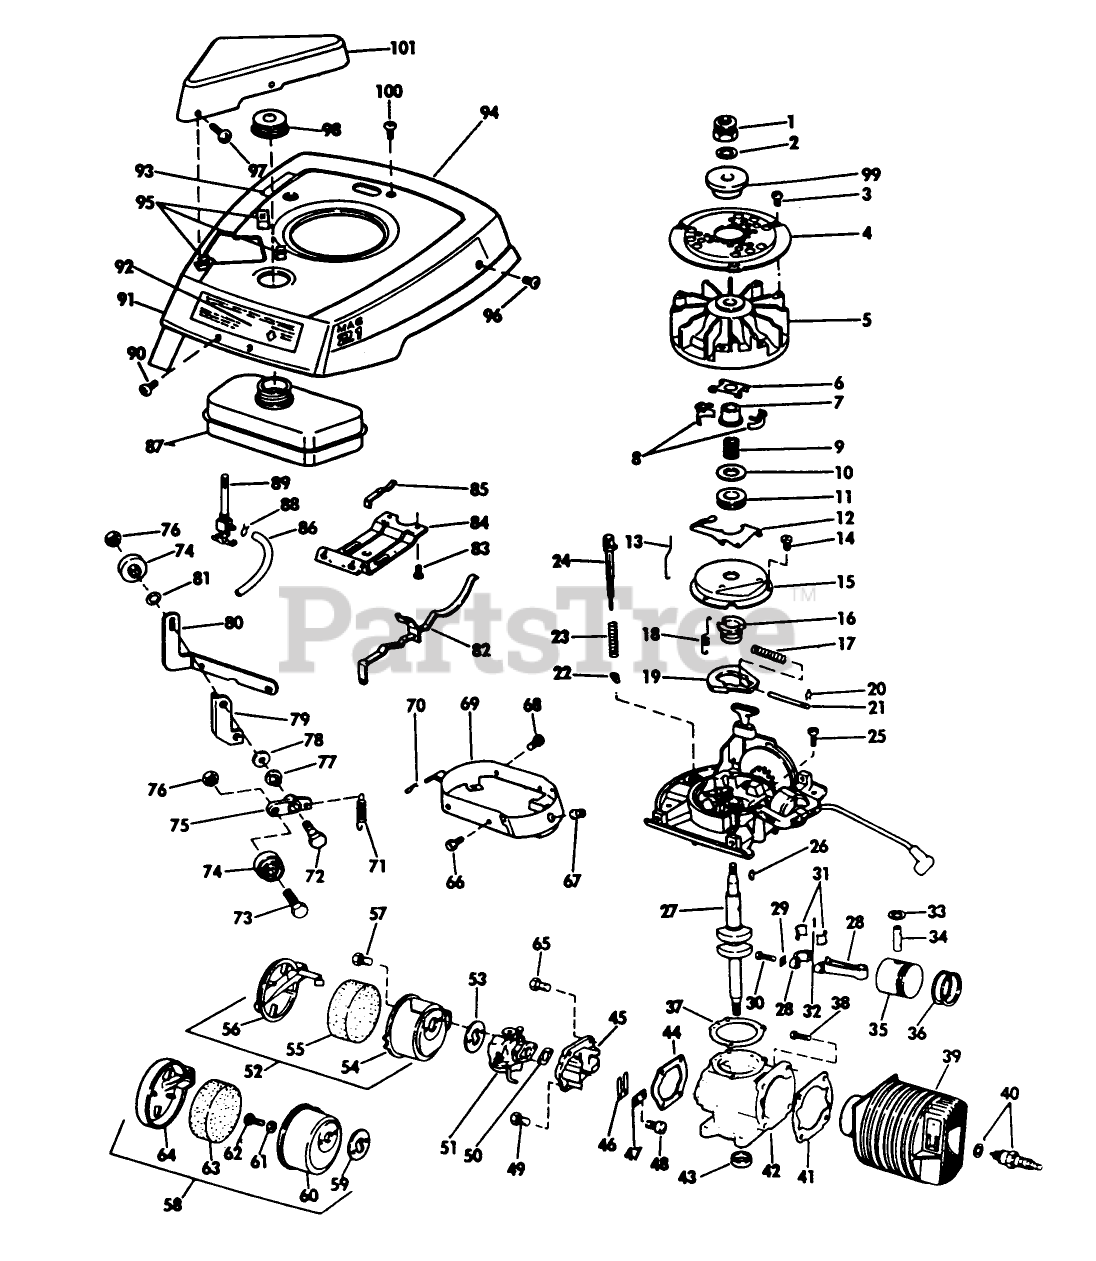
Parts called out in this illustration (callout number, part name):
7	COLLAR S
9	SPRING S
11	THRUST COLLAR S
12	LEVER-GOVERNOR S
14	SCREW S
15	DUST COVER S
16	SPARK ADV. S
17	SPARK ADV. SPRING S
19	FLYWEIGHT S
20	SPARK ADJ. SPRING
21	PIN,SPARK ADV. S
23	SPRING S
31	LINER ASM
33	RING-RETAINING
37	GASKET S
41	GASKET S
47	PLATE-BACKUP, REED
49	SCREW S
50	GASKET S
55	AIR FIL.ELEM S
57	SCREW S
59	GASKET S
60	FILTER CHAMBER S
62	SCREW S
63	AIR FIL.ELEM S
64	CHAMBER AY S
65	SCREW S
66	SCREW S
67	NUT-CLIP
74	IDLER PULLEY
82	SPEED CONTROL
83	SCREW S
86	GAS LINE
88	CLAMP - HOSE S
89	VALVE&SCREEN SM
96	SCREW S
100	SCREW F
